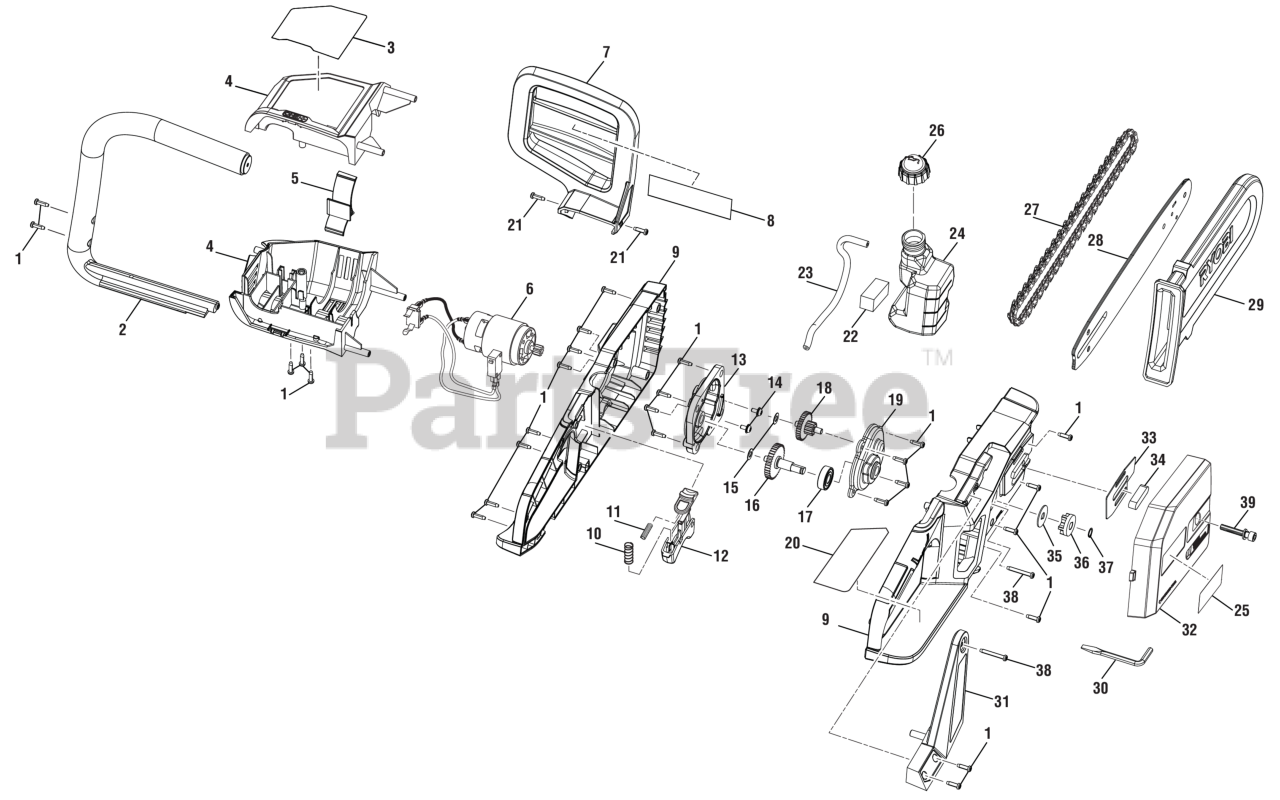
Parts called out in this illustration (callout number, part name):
1	Screw (M4 x 14 mm, T15 Torx Pan Hd.))
2	Front Handle
3	Warning Label
4	Motor Housing Assembly
5	Wind Plate
6	Motor and Wiring Harness Assembly
7	Front Handle Guard
8	Icon Warning Label
9	Housing Assembly
10	Compression Spring
11	Compression Spring
12	Trigger Assembly
13	Gear Box Base Assembly
14	Screw w/Washer (M4 x 8 mm)
15	Washer (ID6.5 x OD13 x 0.5t)
16	Output Gear and Shaft Assembly
17	Ball Bearing (6000 2RS)
18	Input Gear Assembly
19	Gear Box Cover Assembly
20	Data and Warning Label
21	Screw (M4 x 14 mm, Tamper Proof)
23	Outlet Tube
25	Logo Label
26	Oil Cap Assembly
28	Guide Bar
30	Hexagon Key
31	Front Handle Arm
32	Bar Cover w/Chain Tensioner Assembly
33	Rubber Gasket
34	Rubber Plate
35	Cover Plate (Internal "D" Washer)
37	Retaining Ring
38	Screw (M4-18 x 30 mm, T15 Torx Soc. Hd.)
39	Screw w/Washer (M6 x 35 mm, Soc. Hd.)
